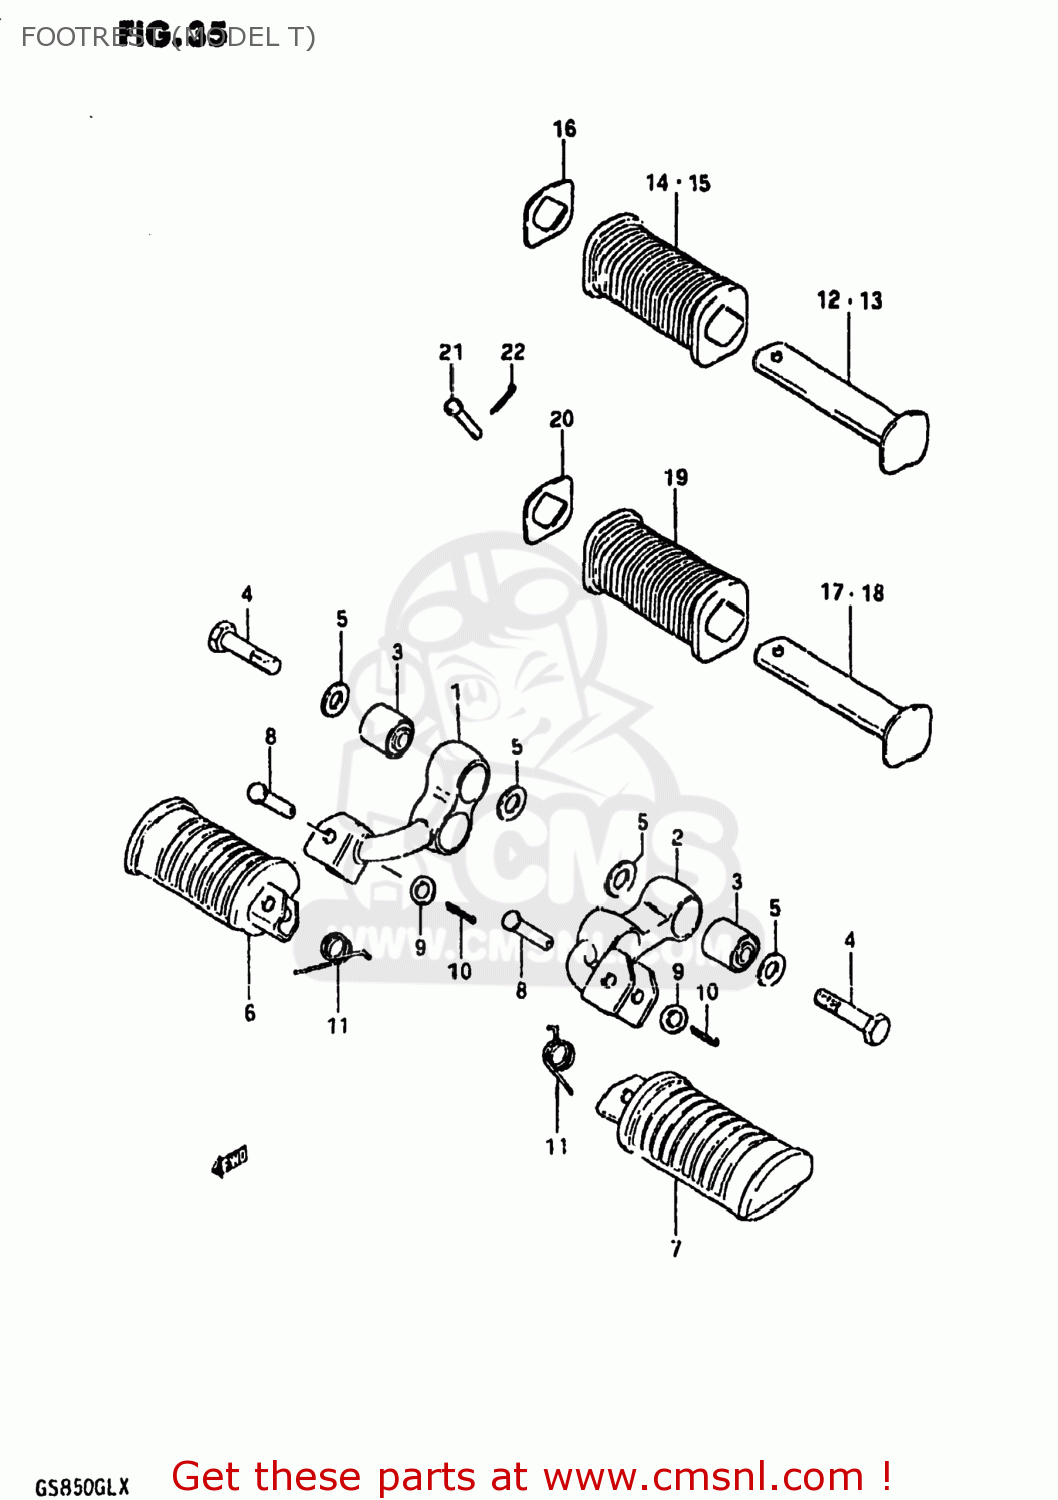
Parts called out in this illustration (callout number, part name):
1	BAR,FRONT FOOTREST,RIGHT
2	BAR,FRONT FOOTREST,LEFT
3	BUSH
4	BOLT
5	WASHER (10.1X21X2.3)
6	RUBBER,FRONT FOOTREST
7	FOOTREST
8	PIN
9	WASHER
10	PIN
11	SPRING
12	BAR,REAR FOOTREST
13	BAR,REAR FOOTREST
14	RUBBER,PILLION FOOTREST
15	RUBBER, LH
16	WASHER,REAR FOOTREST RUBBER
17	BAR,REAR FOOTREST,RIGHT
18	BAR,REAR FOOTREST,LEFT
19	RUBBER,PILLION FOOTREST
20	WASHER,PILLION FOOTREST RUBBER
21	PIN
22	PIN
